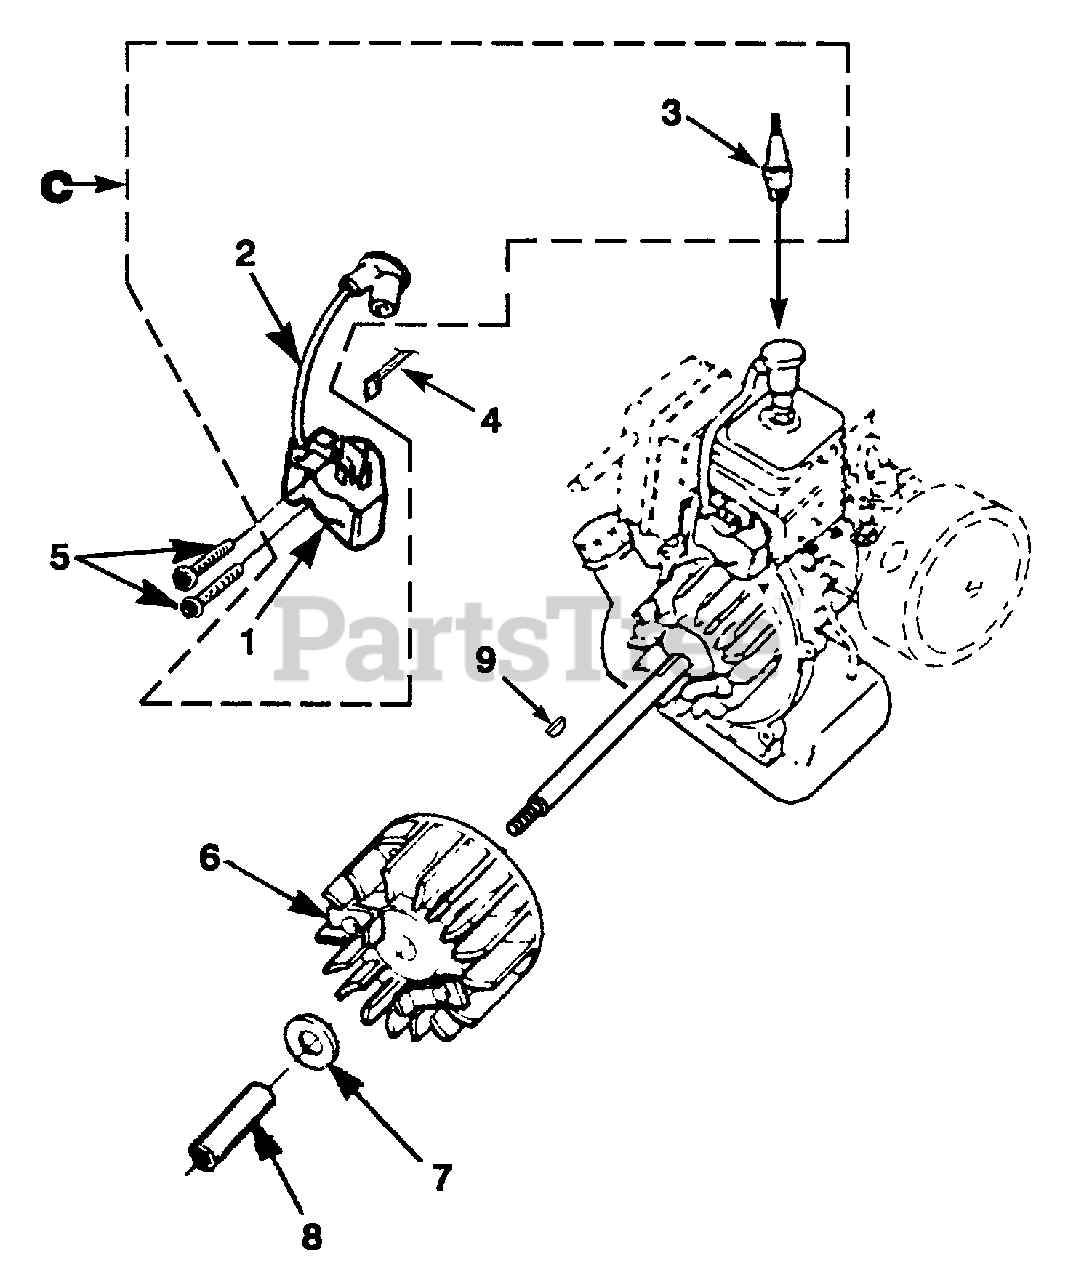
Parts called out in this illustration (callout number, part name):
1	Ignition Module
2	Terminal
3	Spark Plug DJ-7Y
3	Spark Plug
4	Electrical Lead
5	Screw-Thread Forming 8-32 x 1"
6	Rotor
7	Washer-Flat
8	Fan Spacer
9	Woodruff Key
C	Ignition Kit
